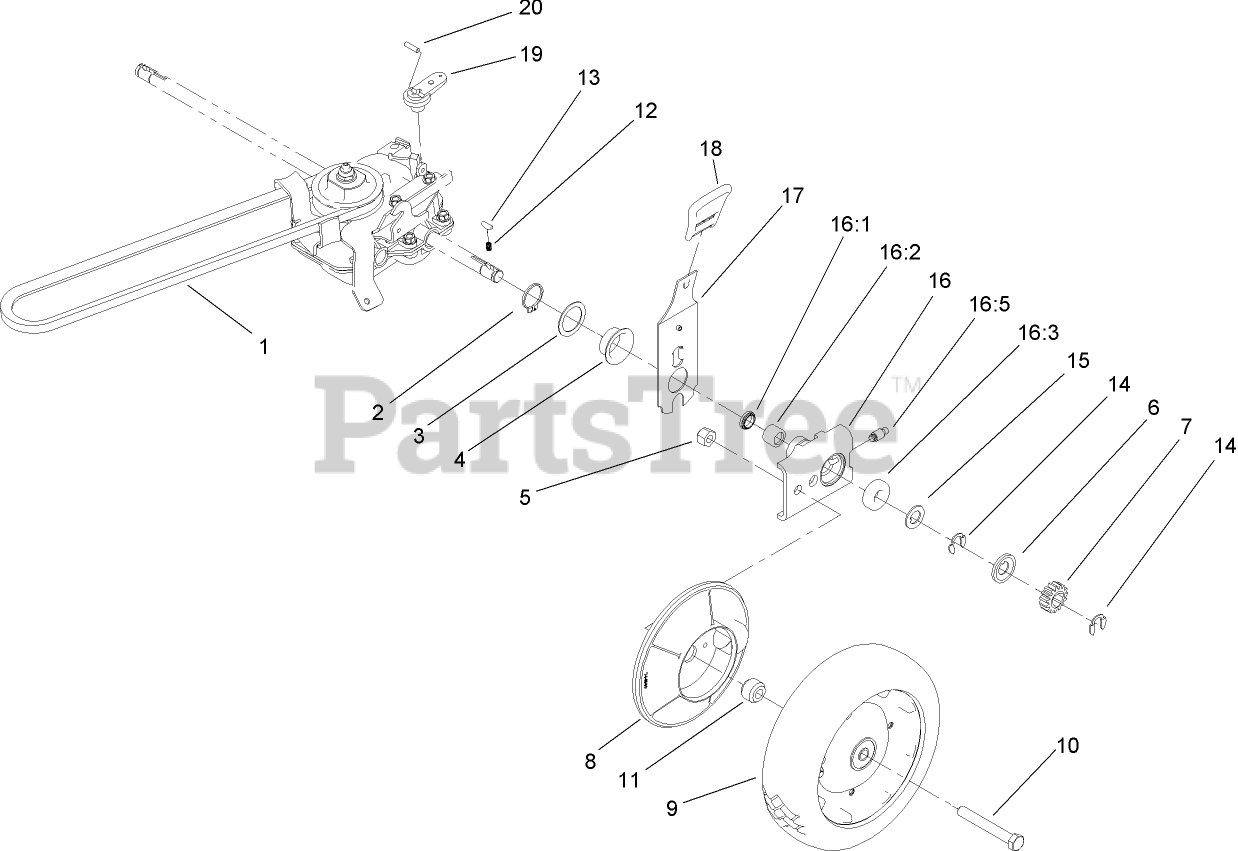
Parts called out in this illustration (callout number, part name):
1	V-BELT
2	RING-RETAINING
3	WASHER
4	CAP-END
5	NUT-LOCK, CONE
6	WASHER-THRUST, OUTER
7	GEAR-PINION
8	COVER-WHEEL
10	SCREW-HH
11	SPACER-COVER, WHEEL
12	SPRING-COMPRESSION
14	RING-RETAINING
15	WASHER-THRUST, OUTER
16	PIVOT ARM ASM
16:1	SEAL-OIL
16:3	BEARING-WHEEL
18	KNOB-HOC
19	LEVER-SHIFT
20	PIN-SPRING
